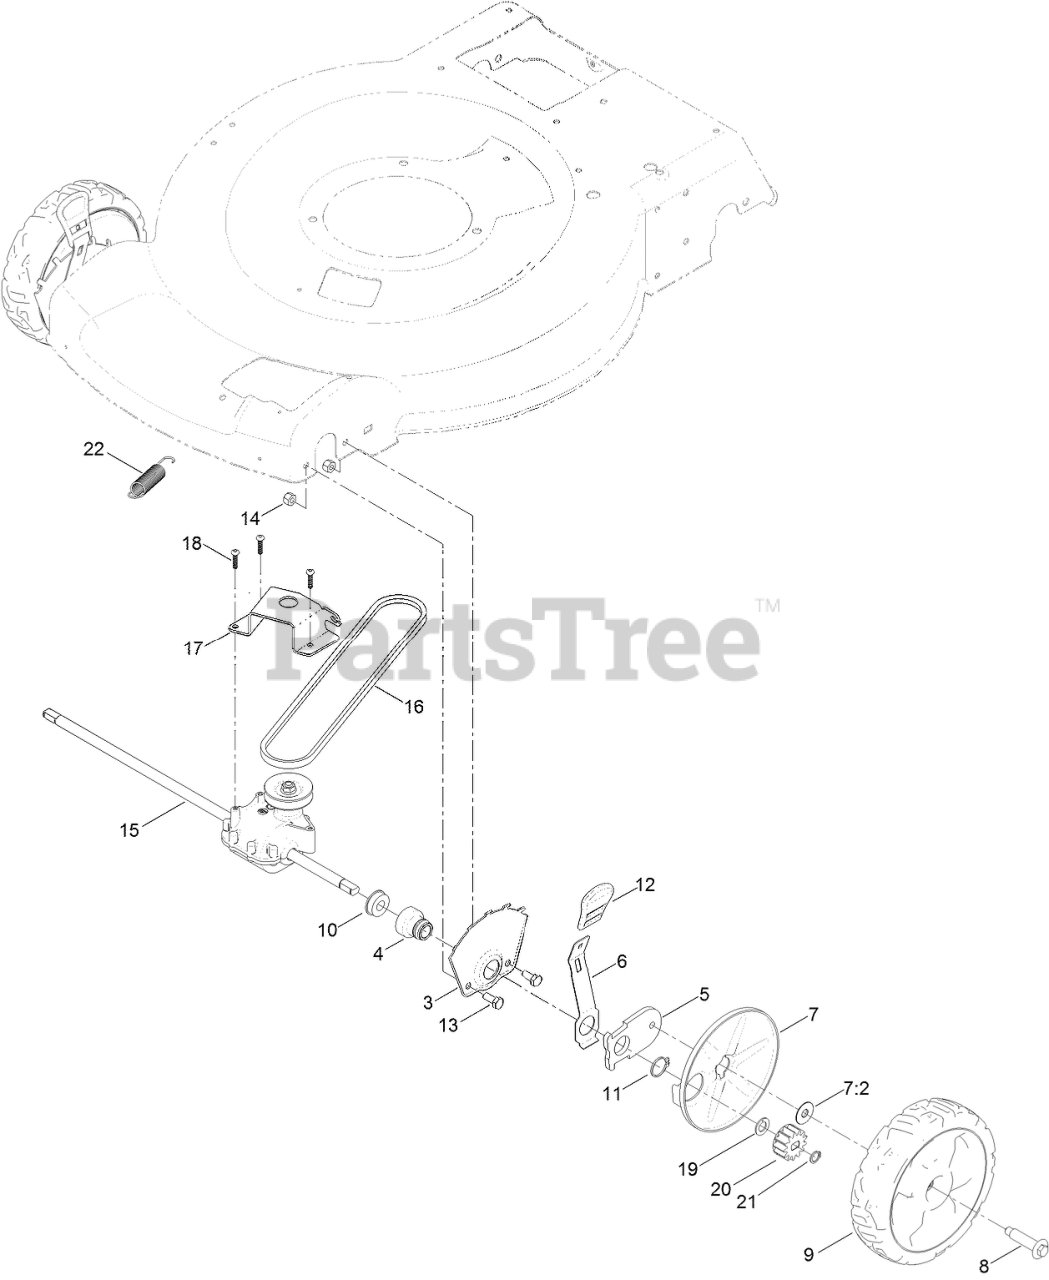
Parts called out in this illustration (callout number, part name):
3	PLATE-HOC, FRONT
4	RETAINER-BEARING, HOC
5	ARM-PIVOT, FRONT
6	Arm-Spring
7	WHEEL COVER ASM
7:2	WASHER-STEPPED
8	BOLT-SHOULDER
9	8 INCH WHEEL ASM (FRONT)
10	BEARING-BALL
11	RING-RETAINING
12	KNOB-HOC
13	SCREW-HH
14	NUT-LOCK, NI
15	TRANSMISSION ASM
16	V-BELT
17	BRACKET-TRANSMISSION
18	SCREW-PLASTITE
19	WASHER-THRUST
20	GEAR-PINION, 13T
21	RING-RETAINING
22	SPRING-EXTENSION
